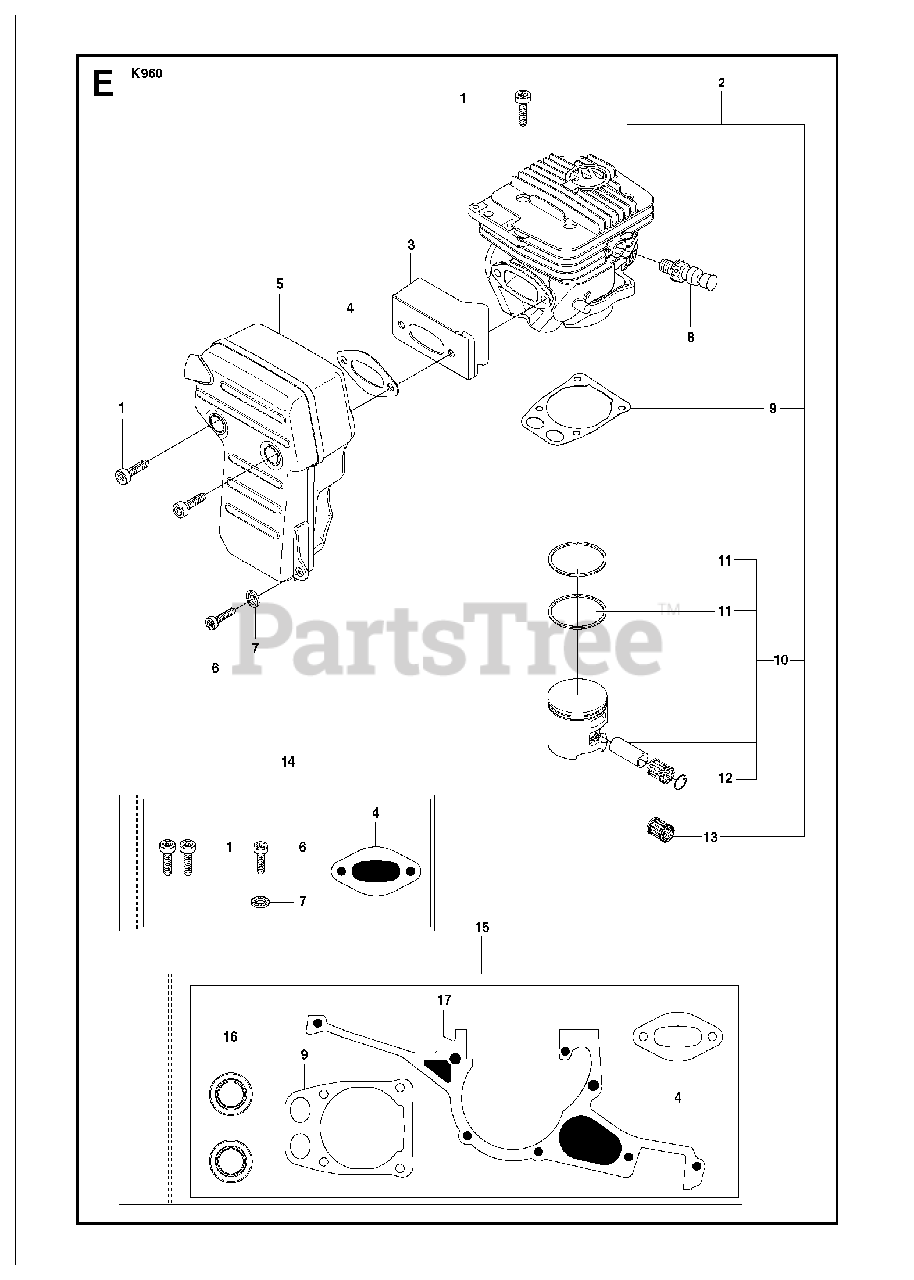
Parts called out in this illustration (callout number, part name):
1	SCREW ITXSCM
2	CYLINDER ASSYIncl. 9, 10, 13
3	HEAT DEFLECTOR
4	GASKET
5	MUFFLER ASSY
6	SCREW ITXSCM
8	DECOMPRESSION VALVE
9	GASKET
10	PISTONIncl. 11, 12
13	NEEDLE BEARING
14	GASKET KITIncl. 1, 4, 6, 7
15	GASKET KITIncl. 4, 9, 16, 17
16	SEALING RING
17	GASKET
